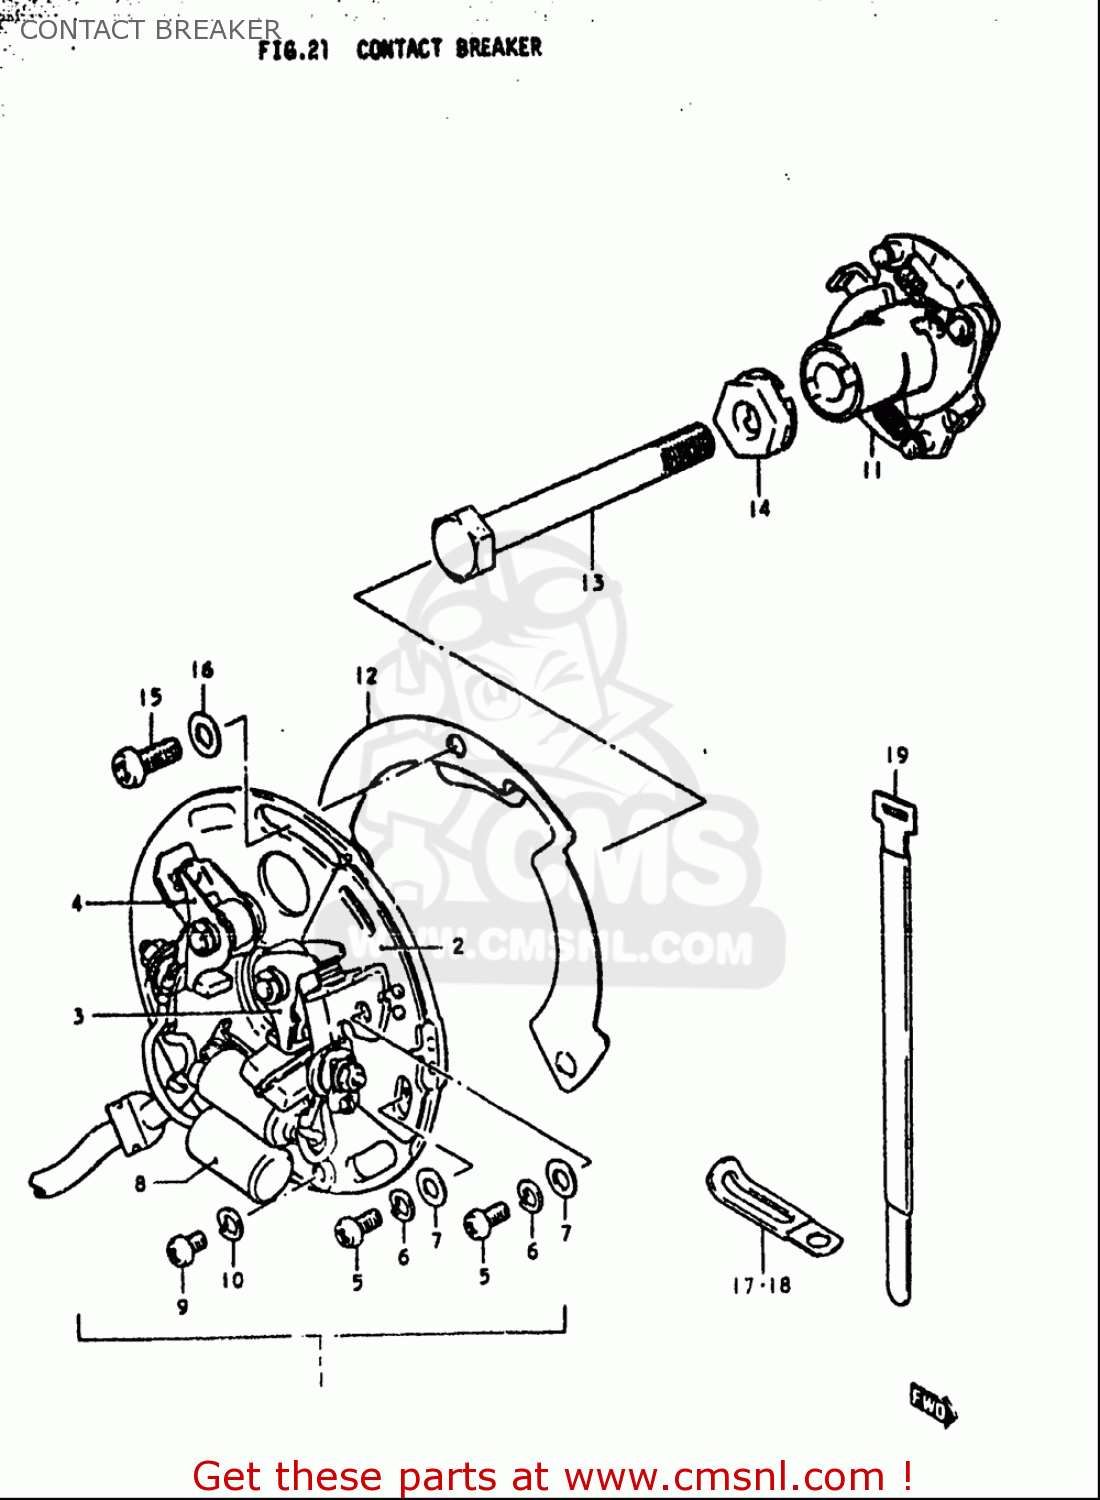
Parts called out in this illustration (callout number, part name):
1	BREAKER ASSEMBLY,CONTACT
2	PLATE,CONTACT POINT
3	POINT ASSY,R
4	POINT ASSY,L
5	SCREW(4X10)
6	WASHER,LOCK
7	WASHER
8	CONDENSER
9	SCREW 4X6
10	WASHER,LOCK
11	GOVERNOR ASSEMBLY
12	PLATE,IGNITION TIMING
13	BOLT
14	WASHER
15	SCREW(5X12)
16	WASHER
17	CLAMP(L:65)
18	CLAMP(L:120 T:1.0)
19	CLAMP
